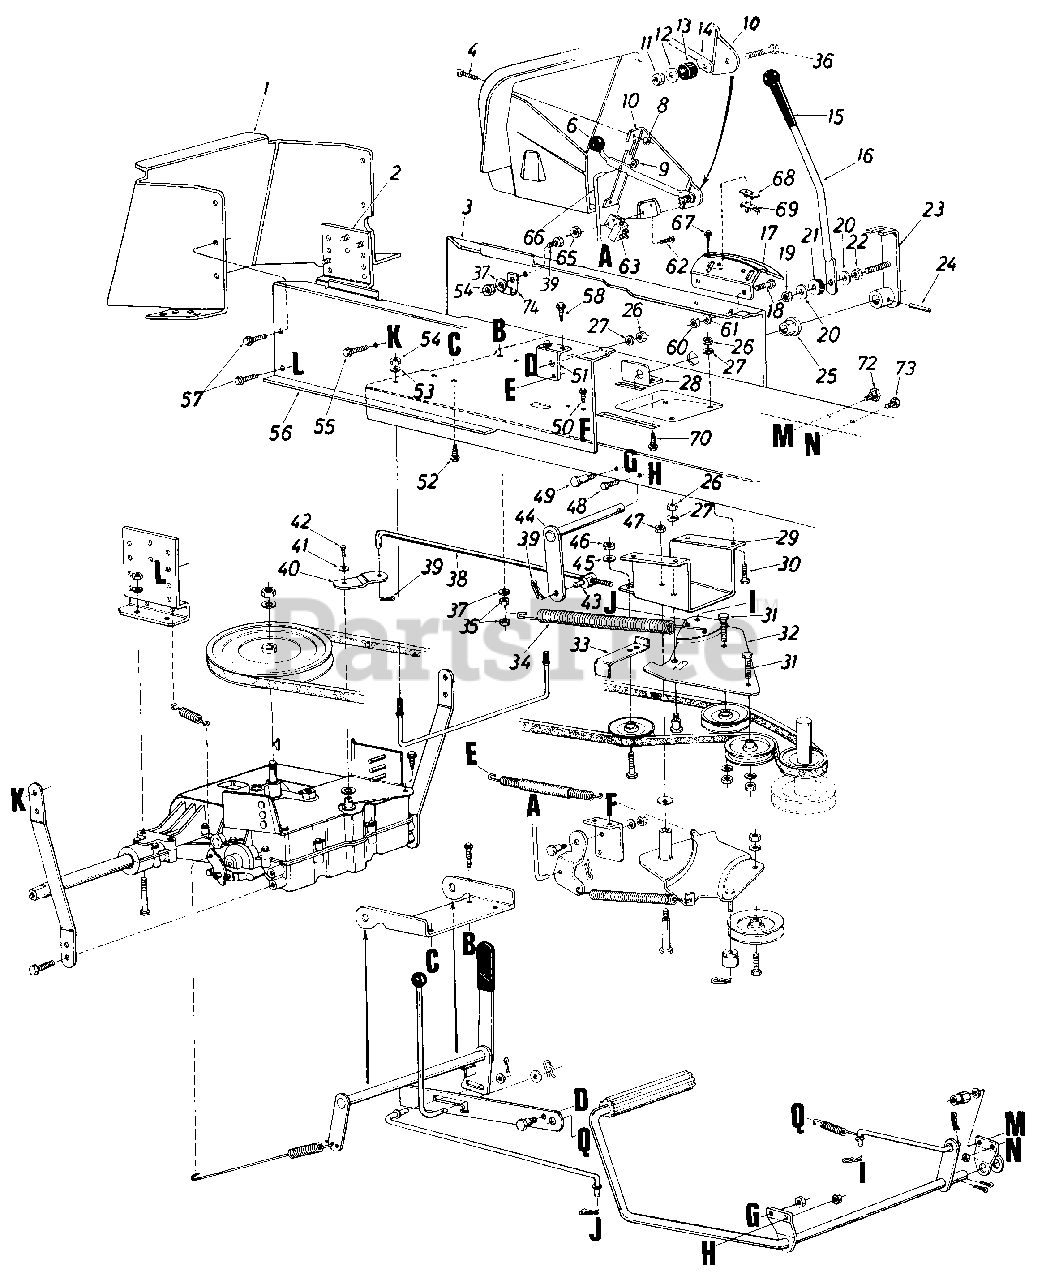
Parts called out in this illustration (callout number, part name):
3	Side Panel Upper Frame L. H.
4	Truss. Mach. Scr. 1/4-20 x .50" Lg.
6	Ball Knob
8	Hex Sems Nut 1/4 20 Thd
9	Push Cap 1/4" Rod
10	Deck Clutch Control Brkt.
11	Hex Cent. L-Nut 1/4-20 Thd.
12	Fl-Wash .281" I.D. x .734" O.D. x .063 Thk.
13	1 Rubber Wash. .330" I.D. x .87" O.D. x .32 Thk.
14	Blade Clutch Lever
16	Shift Lever
19	Hex Cent. L-Nut 5/16-18 Thd.
20	Fl-Wash. .344" I.D. x .875" O.D. x .063 Thk.
21	Rubber Wash. .330" I.D. x .87" O.D. x .32 Thk.
22	Hex Nut 5/16-18 Thd.
23	Handle Mount Brkt. Ass'y.
24	Spring Pin Spiral 1/4" Dia. x 1.5" Lg.
25	Plastic Hex Bearing .625" I.D.
26	Hex Nut 5/16-18 Thd.
27	L-Wash. 5/16" I.D.
28	Speed Control Shaft Brkt.
29	Transaxle Clutch Support Brkt.
30	Hex Bolt 5/16-18 x 1.0" Lg.
31	Hex Bolt 3/8-24 x 1.5" Lg.
32	Idler Bracket Ass'y.
35	Hex Cent. L-Nut 1/4-20 Thd.
36	Hex Bolt 1/4-20 x .625" Lg.
37	L-Wash. 1/4" I.D.
38	Shift Link
39	Hairpin Cotter 3/8"
40	Shifter Bracket
41	Belleville Wash. .25" I.D. x.375" O.D.
42	Hex Bolt 1/4-28 x .6" Lg.
43	Pivot Bushing
44	Speed Control Shaft Ass'y.
45	Fl-Wash. .385" I.D. x .87" O.D. x .060 Thk.
46	Hex Cent. L-Nut 3/8-24 Thd.
47	Hex Cent. L-Nut 3/8-16 Thd.
48	Hex Bolt 3/8-16 x .62" Lg.
49	Shoulder Bolt .500" Dia. x .340" Lg. (3/8-16)
50	Hex Thd. Rolling Scr. 1/4-20 x.50" Lg.
51	Parking Brake Cam Mtg. Brkt.
52	Hex Thd. Rolling Scr. 1/4-20 x.50" Lg.
53	L-Wash. 1/4" I.D.
54	Hex Nut 1/4-20 Thd.
55	Hex Wash. Hd. TT-Tap Scr. 3/8-16 x .5" Lg.
56	Side Panel Upper Frame-R.H.
57	Hex Thd. Rolling Scr. 5/16-24 x .50" Lg.
58	Hex Thd. Rolling Scr. 1/4-20 x.50" Lg.
60	Hex Nut 5/16-18 Thd.
61	L-Wash. 5/16" I.D.
62	Truss Mach. Scr. #10-24 x .50" Lg.
63	Safety Switch
65	Hex Nut #10-24 Thd.
66	Deck Control Rod
67	Hex Wash. Hd. Scr. #8 x .50" Lg.
68	Insulator Nut Plate
69	Spring Switch
70	Hex Wash. Hd. AB-Tap Scr. 5/16 x .75" Lg.
72	Shld. Bolt .498" Dia. x .34"
73	Hex Bolt 3/8-16 x .62" Lg.
74	Clamp
